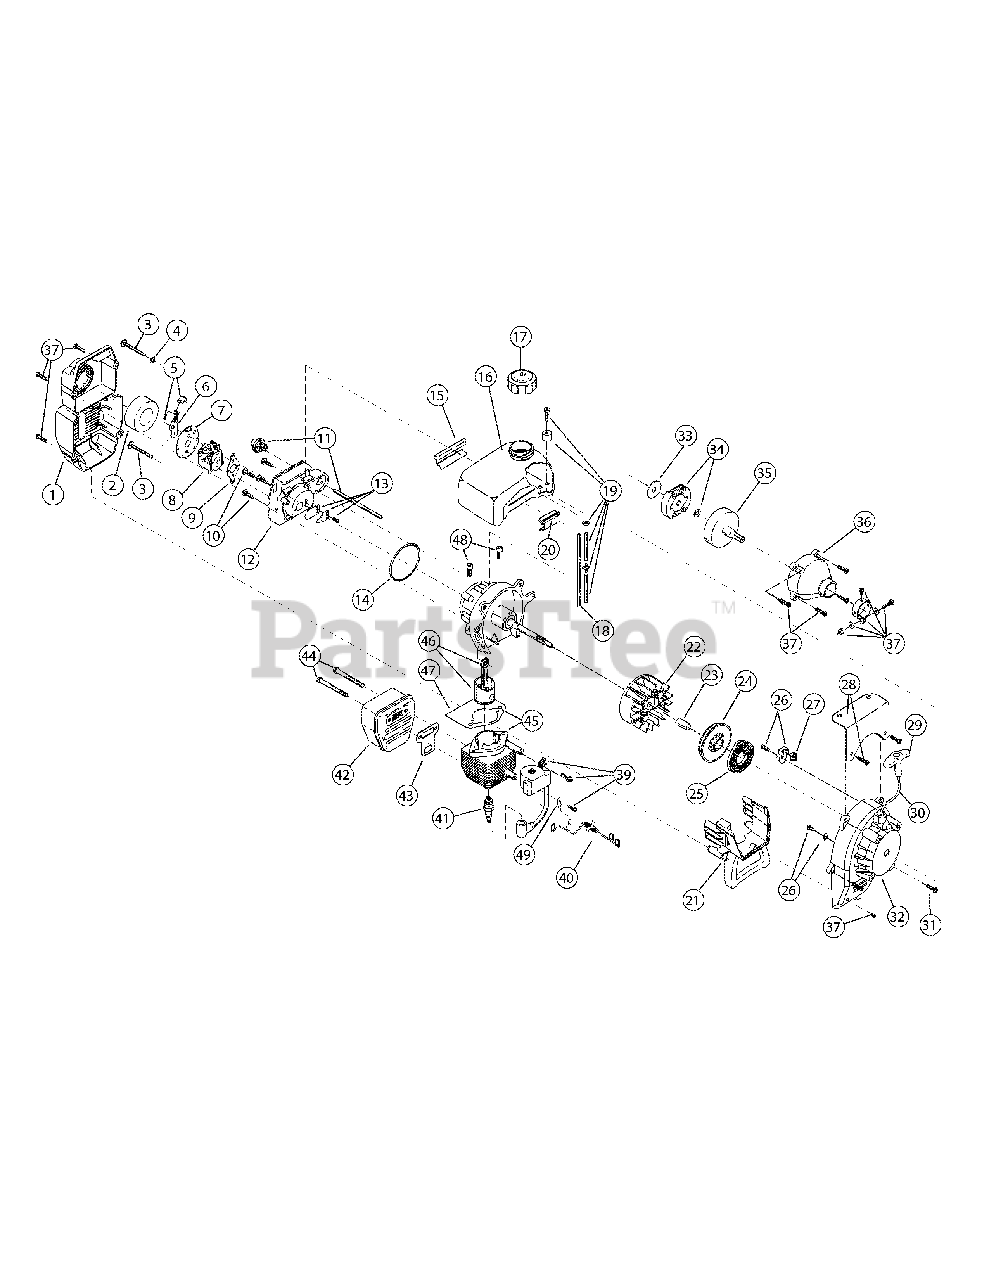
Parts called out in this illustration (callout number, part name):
1	Air Cleaner Assembly
2	Air Cleaner Filter
3	Carburetor Mounting Screw Assembly
4	Wavey Washer
5	Choke Knob & Screw
6	Choke Lever Assembly
7	Choke Lever & Plate
8	Carburetor Assembly
9	Carburetor Gasket
10	Carb Mount Screw
11	Primer and Hose Assembly
12	Carb Mount Assembly
13	Reed Assembly
14	Carburetor Mount Gasket
15	Rear Mounting Pad
16	Fuel Tank Assembly
17	Fuel Cap Assembly
18	Fuel Return Line
19	Fuel Line Assembly
20	Front Mounting Pad
21	Shroud Extension and Stand
22	Flywheel Assembly
24	Recoil Pulley
25	Recoil Spring
26	Pulley Retainer Assembly
27	Rope Guide
28	Fuel Tank Guard Assembly
29	Pull Handle
31	Housing Screw
32	Starter Housing Assembly
33	Clutch Washer
34	Clutch Rotor Assembly
35	Clutch Drum Assembly
36	Clutch Cover Assembly
37	Clutch Cover Screw
38	Upper Clamp Assembly
39	Module Assembly
40	Wire Lead
41	Spark Plug
42	Muffler Assembly
43	Exhaust Gasket
44	Muffler Mounting Bolt Assembly
45	Cylinder Assembly
46	Piston & Rod Assembly
47	Cylinder Gasket
48	Cylinder Bolt
49	Ground Tab
